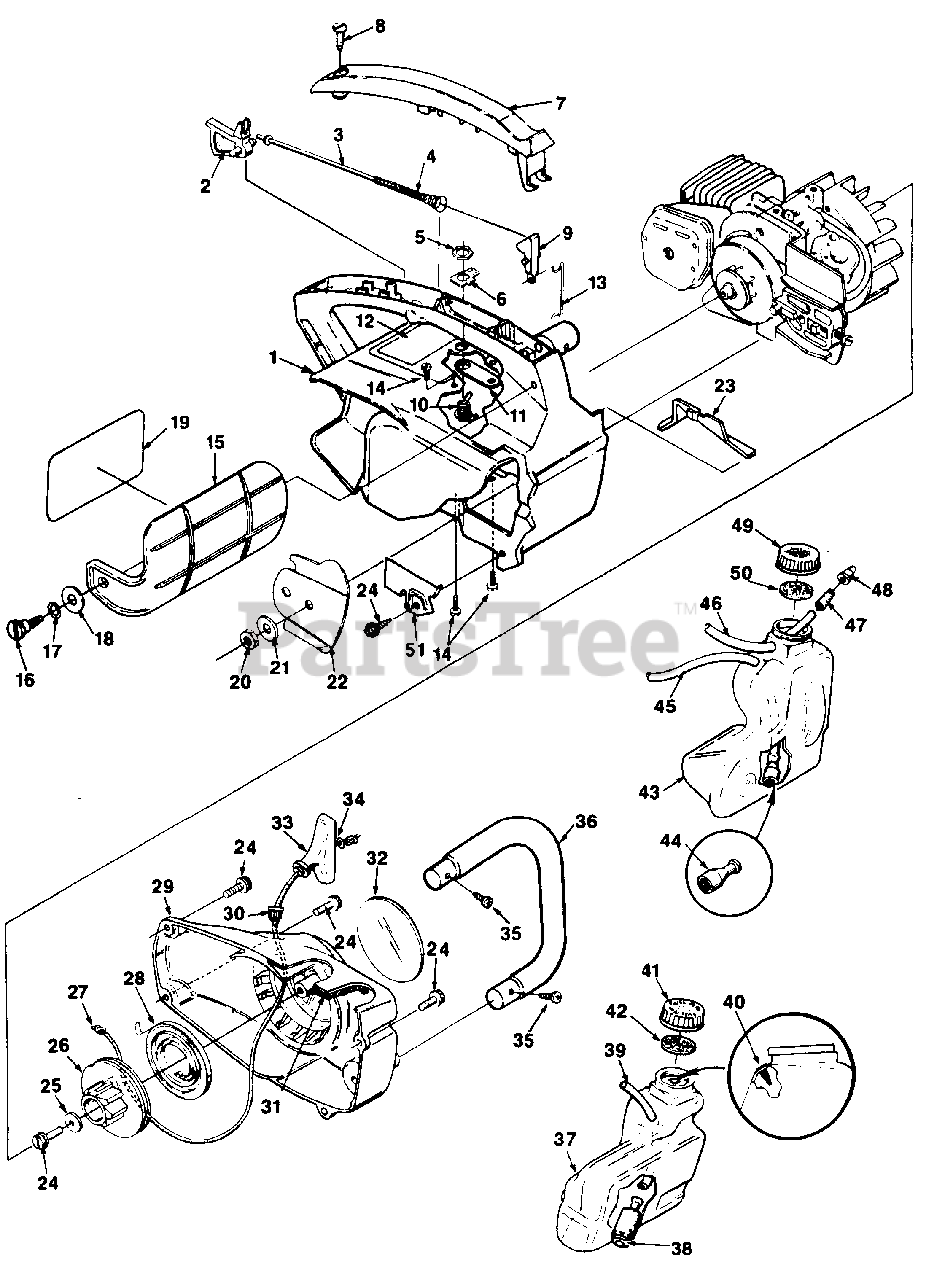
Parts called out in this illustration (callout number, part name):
1	HOUSING- Engine
2	TRIGGER- Rear
3	ROD- Throttle
4	SPRING- Throttle rod
5	NUT- Hex
6	PLATE-"ON"-"OFF"
7	COVER- Handle
8	SCREW- Thread forming (10 x 625)
9	LEVER- Throttle
10	SWITCH & LEAD
11	STRAP- Ground
12	PLATE- Starting instruction
13	ROD- Front throttle
14	SCREW- Hex hd.
15	GUARD- Hand
16	SCREW- Shoulder
17	WASHER- Belleville
18	WASHER- Flat
19	DECAL
20	NUT- Guide bar 1/4-28
21	WASHER- Flat
22	PLATE- Guide bar
23	COVER- Air filter
24	SCREW- Thread forming
25	WASHER- Retaining
26	PULLEY- Starter
27	ROPE- Starter
28	SPRING & CONTAINER
29	STARTER HOUSING ASSY.
30	BUSHING- Starter housing
31	FILTER- Fuel tank valve
32	DECAL- (XL)
33	GRIP- Starter
34	WASHER- Flat
35	SCREW- Thread forming
36	HANDLE BAR
37	TANK- Fuel
38	FILTER- Fuel
39	LINE- Fuel 7 1/4"
40	VALVE- Check (Duck bill)
41	CAP- Fuel tank (red)
42	GASKET- Fuel cap
43	TANK- Oil
44	FINDER- Oil
45	LINE- Oil (6")
46	LINE- Pressure
47	CONNECTOR- Oil
48	VALVE- Check (Duck bill)
49	CAP- Oil (Black)
50	GASKET- Fuel filler cap
51	GUARD- Chain
